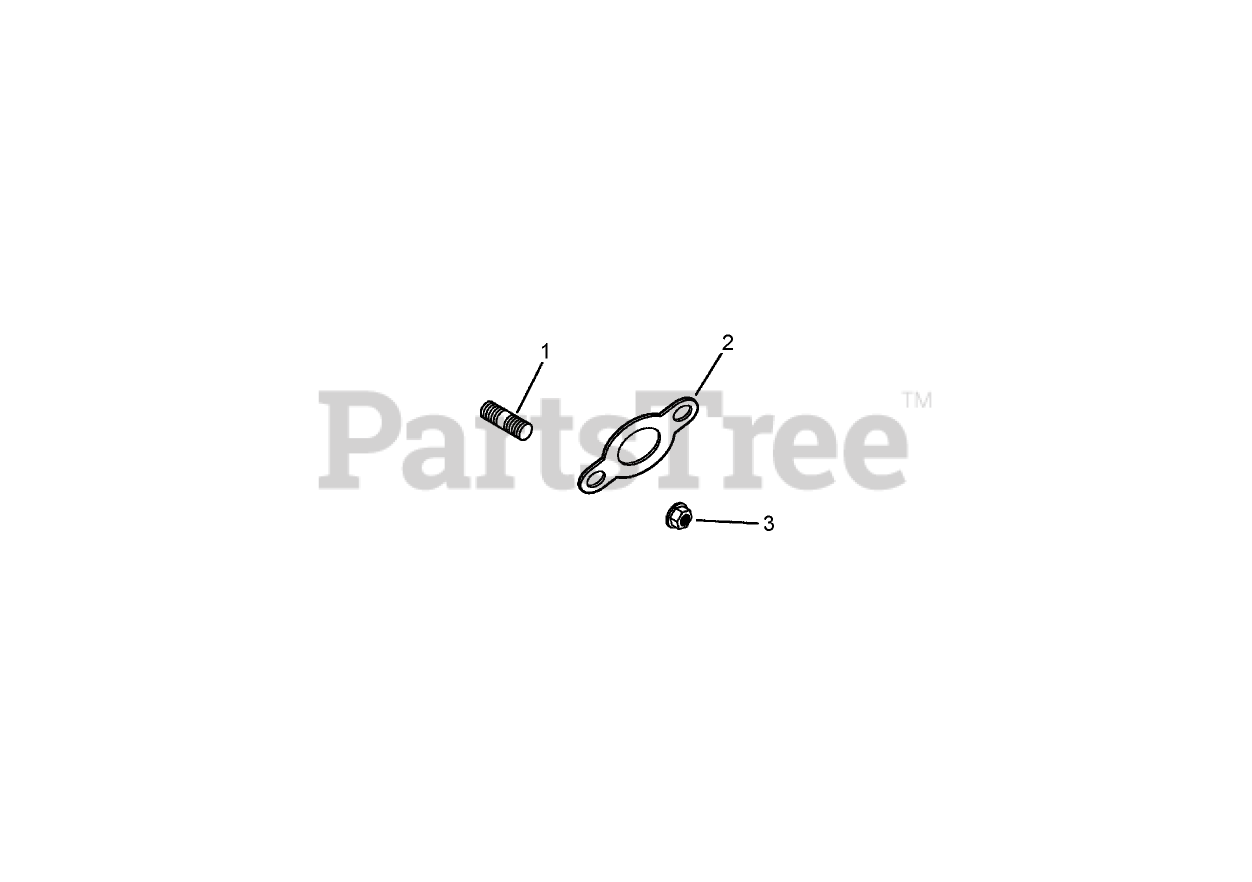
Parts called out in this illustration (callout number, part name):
1	STUD (M8X1.25X33)
2	GASKET-EXHAUST
3	NUT-FLANGE (M8X1.25)
